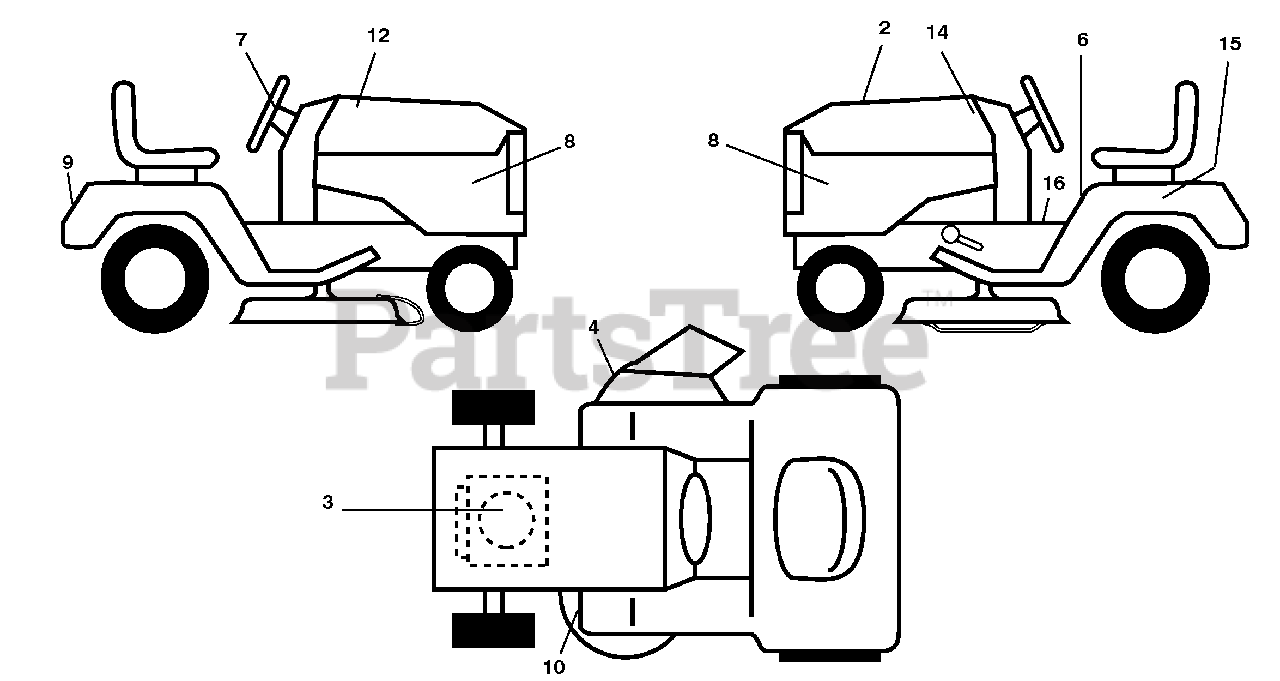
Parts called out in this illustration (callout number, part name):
2	Decal, Replacement
3	Decal, Engine HP
4	Decal Warning
6	Decal, Fender Danger English
7	Decal Ins Str Wh
8	Decal, Side Panel
9	Decal, Fender
10	Decal, V-Belt Sch.
12	Decal, Hood RH
14	Decal, Hood LH
15	Decal, Caution, Battery
16	Decal, Oper
16	Decal, Handle Lft Height Adj.
16	Manual, Operator's (E&F)
16	Manual, Parts (E&F)
